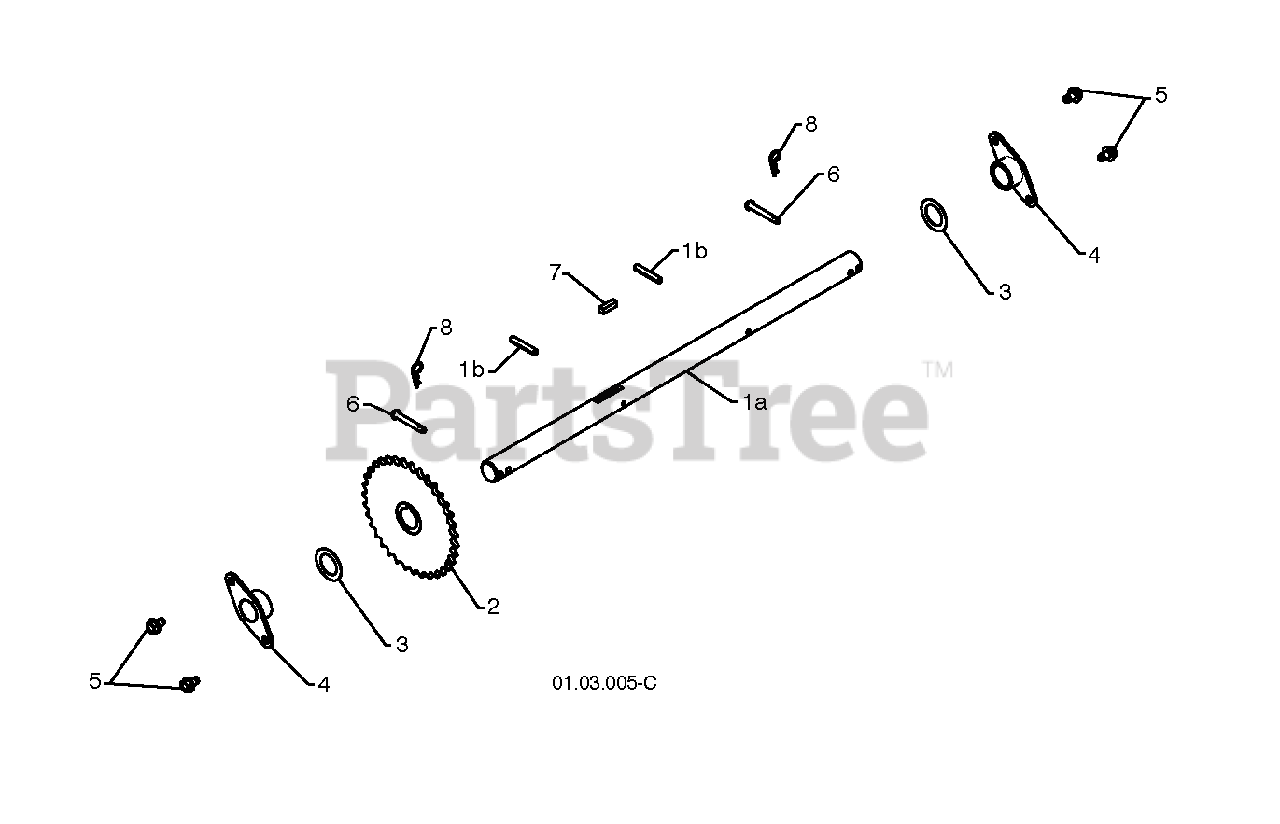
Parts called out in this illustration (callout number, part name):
1	AXLE.SHAFT.ASM.W/ROLPIN.NON-PS
2	SPROCKET.WELDMENT.AXLE.1.00
3	WASHER 1.00
4	BEARING, AXLE
5	SCREW LT
6	RIVET
7	KEY, SQUARE 1/4 X .875
8	RETAINER M
